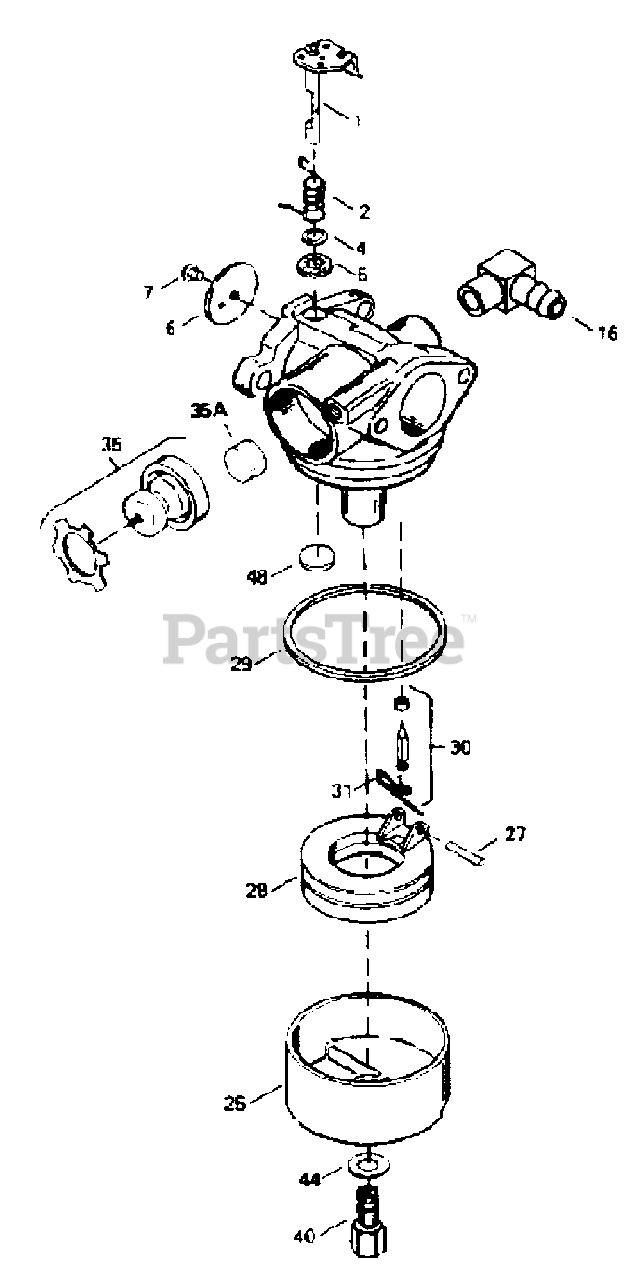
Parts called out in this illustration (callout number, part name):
1	Throttle Shaft & Lever Assembly
2	Throttle Return Spring
4	Dust Seal Washer
5	Dust Seal (Throttle)
6	Throttle Shutter
7	Shutter Screw
16	Fuel Fitting
25	Float Bowl
27	Float Shaft
29	Float Bowl "O" Ring
30	Inlet Needle, Seat, & Clip (Incl. 31)
31	Spring Clip
35	Primer Bulb/Retainer Ring
35A	Primer Bulb Filter
40	High Speed Bowl Nut
44	Bowl Nut Washer
48	Welch Plug, Atmospheric Vent
